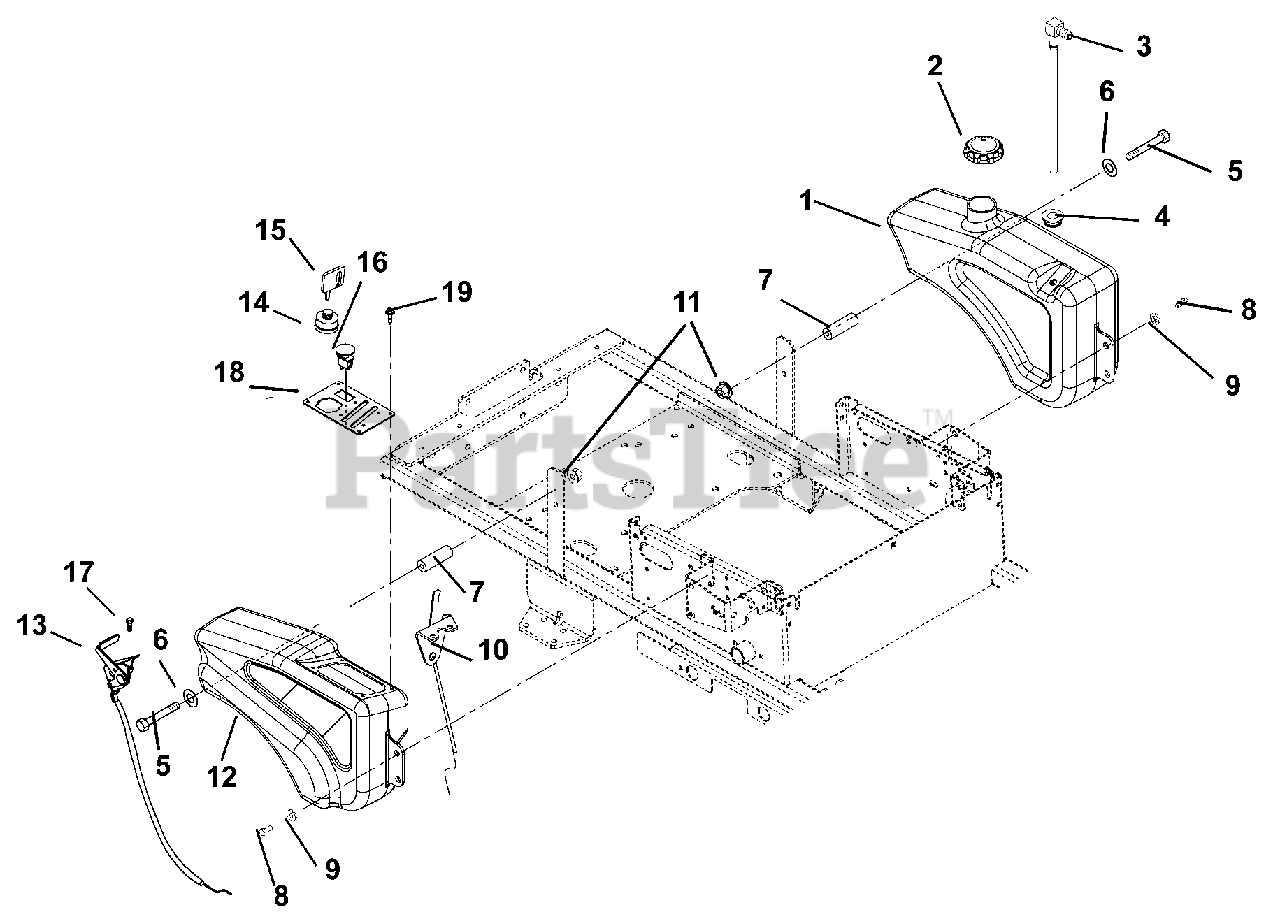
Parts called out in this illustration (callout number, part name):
1	Gas Tank
2	Fuel Cap
3	Fitting, Tank
4	Bushing, Flange .375 x 1.062 x .625
5	Bolt, Hex .31-18 x 3.50 Grade 5
6	Washer, Flat-Steel .38 x .875 x .083
7	Spacer, Tank Mount
8	Bolt, Hex .31-18 x .75 Grade 5
9	Shoulder Spacer
10	Cable, Choke Cable (094, 096)
11	Nut, .31-18 Nyloc Flange
13	Cable, Throttle (094, 096)
14	Key Switch
15	Key, w/cap
16	Switch, Clutch
17	Screw, Tapping 10-24 x .50 Hex Washer Head (094, 096)
18	Control Panel (094, 096)
19	Rivet, Plastic .195 Diameter
